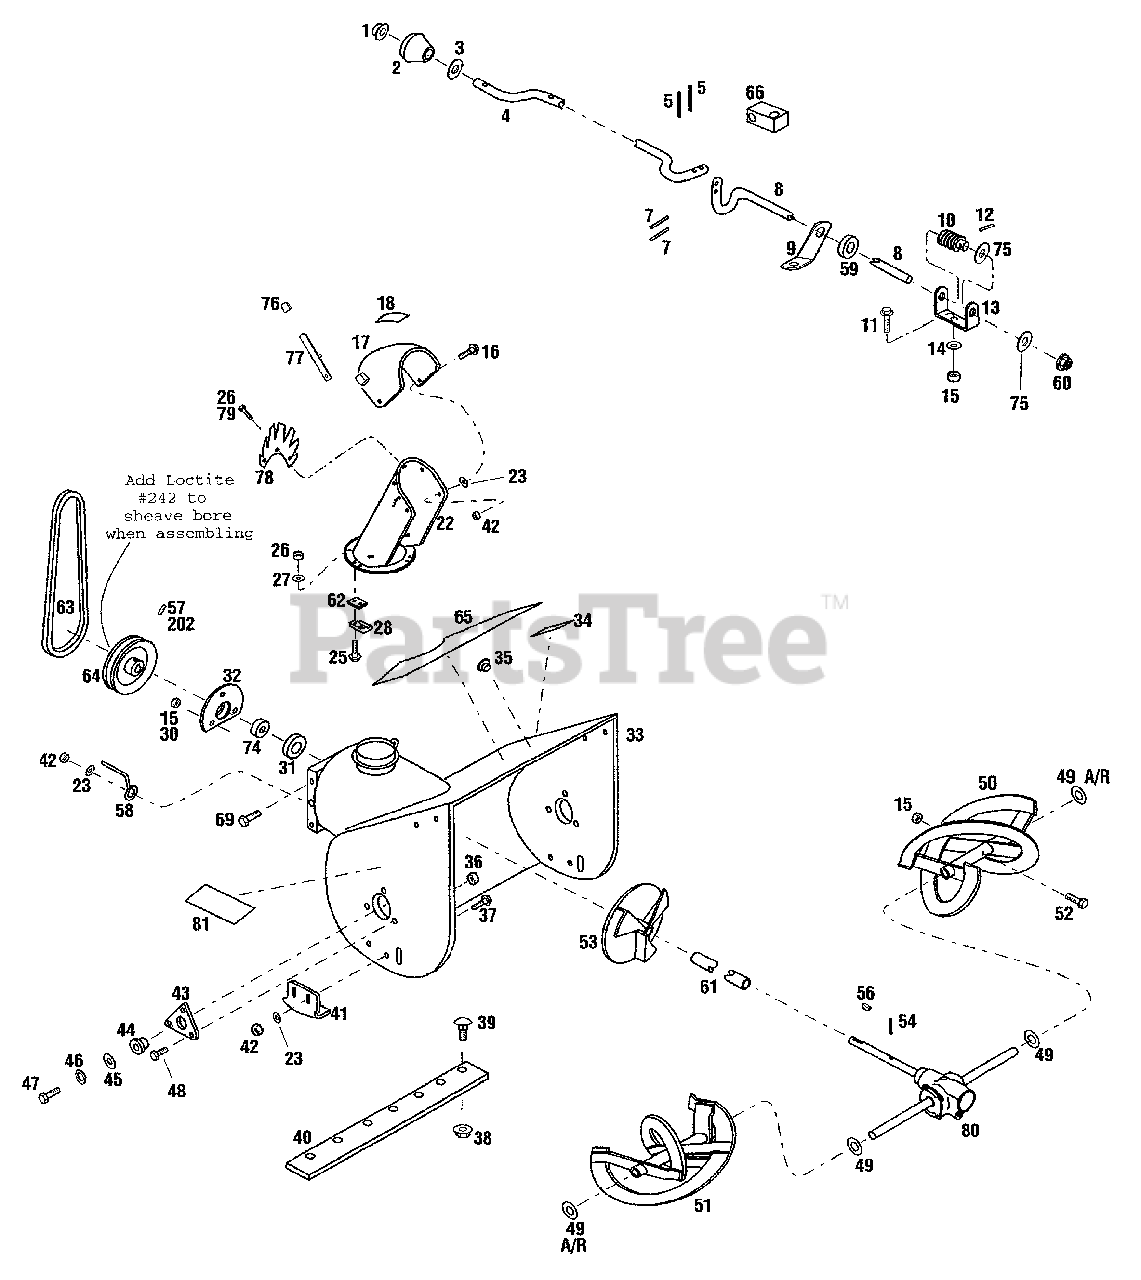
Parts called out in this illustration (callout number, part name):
1	Push-On Cap
2	Knob
3	Flat Washer, 3/8
4	Chute Control Crank
5	Cotter Pin, 3/32 x 5/8
7	Roll Pin, 118 x 3/4
8	Chute Control Shaft
9	Crank Support
10	Worm Gear
11	Flange Screw, 5/16 -18 x 3/4
12	Drive Pin, 3/32 x 3/4
13	Gear Support
14	Flat Washer, 5/16
15	Locknut, 5/16-18
16	Hex hd. Screw, 3/8-16 x 3/4
17	Cap Assembly
18	Warning Decal
23	Flat Washer, 3/8
25	Sems Screw, #10-24 x 7/8
26	Locknut, #10-24
27	Flat Washer, #10
28	Hold Down Clip
30	Hex hd. Screw, 5/16-18 x 5/8
31	Ball Bearing
32	Bearing Retainer
33	Housing Assembly
34	Warning Decal
36	Locknut,1/4-20
37	Carriage Bolt, 3/8-16 x 3/4
38	Flange Locknut, 5/16-18
39	Carriage Bolt, 5/16-18 x 1/2
40	Scraper Blade
41	Skid Shoe
42	Locknut,3/8-16
43	Support Bearing
44	Flange Bushing
45	Flat Washer, 1/2
46	Lockwasher,1/2
47	Hex Bolt, 1/2-13 x 3/4
48	Hex Bolt, 1/4-20 x 5/8
49	Special Washer
50	Left Auger Blade
51	Right Auger Blade
52	Shear Bolt, 5/16-18
53	Impeller
54	Roll Pin, 1/4 x 1-1/4
56	Key, 3/16 x 3/4
57	Square Set Screw, 5/16-18 x 5/8
58	Belt Guide
59	Nylon Bushing
60	Flange Nut
61	Sleeve
64	Auger Sheave
65	Logo Decal
66	Swivel Block
69	Flange Bolt, 5/16-18 x 3/4
74	Shim Washer
75	Nylon Washer
77	Adjusting Lever
78	Chute Deflector
79	Truss Head Bolt, 10-24
80	Gear Case Assembly
81	Logo Decal
202	Loctite #242, .02 oz.
